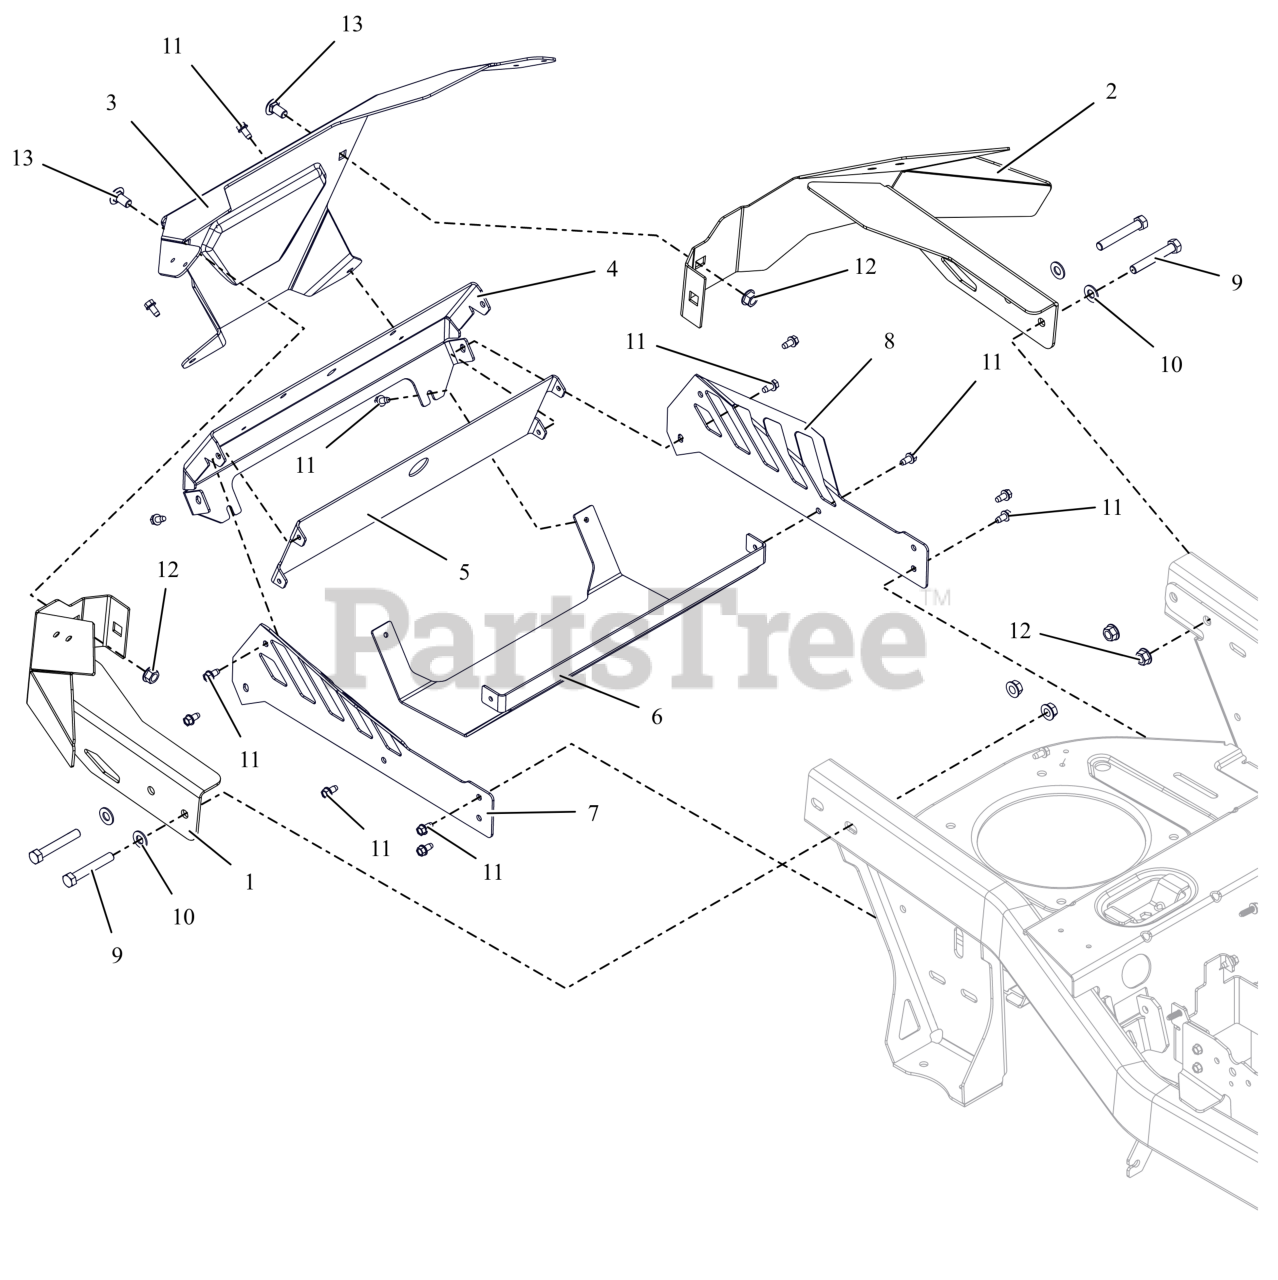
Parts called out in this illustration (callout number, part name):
1	WLDMT, BUMPER - RH (BLACK)
2	WLDMT, BUMPER -LH (BLACK)
3	PLATE, BACK WRAP-ARIENS (BLACK)
4	SHIELD- MUFFLER
5	SHIELD- HEAT
6	MUFFLER- SHEILD- GRASS BROWN
7	KIT, RH MUFFLER GUARD W/ DECALS
8	KIT, LH MUFFLER GUARD W/ DECALS
9	BLT, HEX .38-16X2.50 G5 ZCC
10	WSHR,FLT .406X.812X.065 ZCC
11	SCR-TAP .25X.50 HWH ZB500
12	NUT-LK-CTR-FLG .375-16 GF ZCC
13	BTL,RHSSN .375-16 X 0.75 G5 FPB
